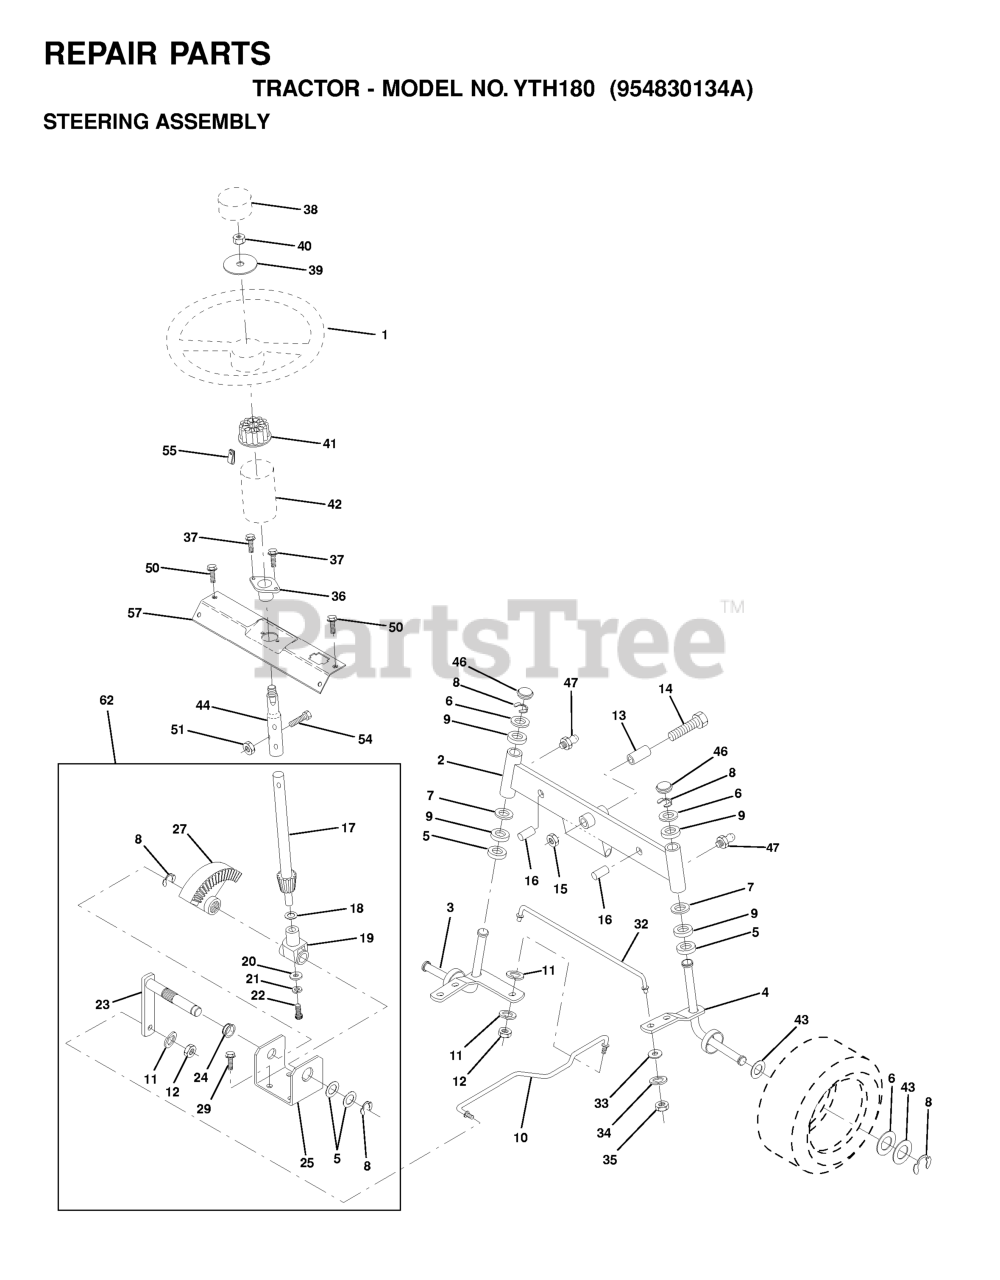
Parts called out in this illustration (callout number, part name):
1	STEERING WHEEL
3	SPINDLE LH
4	SPINDLE RH
5	THRUST WASHER
9	BRNG T
10	LINK.DRAG.SOL.BALL JT.20.064
11	WASHER, LOCK 3/8
12	NUT
13	BEARING
14	Bolt, Hex Head 5/8-11 x 3-1/2
15	NUT-LOC,FLANGE LT
17	SHAFT STEERING
18	THRUST WASHER
19	SHAFT,SUPPORT
20	WASHER
21	LOCKWASHER
22	SCREW,SPECIAL
23	SHAFT PITMAN
24	NYLINER T (7283A)
25	BRKT,STEERING
27	GEAR.SECTOR
29	SCREW
32	TIE ROD
33	WASHER M
34	WASHER.LOCK.HVY.HLCL.SPR.5/16
35	LOCKNUT
36	BUSHING-STRG LT
37	SCREW LT
38	INSERT,STR WHEEL
39	WASHER T
40	GRIPCO NUT
41	ADAPTER-WHEEL LT
42	BOOT, STEERING SHAFT
44	STEERING SHAFT
46	CAP.SPINDLE.BLACK
47	ZERK M
50	SCREW HEX CRT
51	NUT.71038.31-18.HEX.NYLOCK
54	BOLT.5/16-18X1-1/4 FULL.THREAD
57	SUPPORT STEERING SHAFT
62	KIT, STEERING ASSEMBLY
